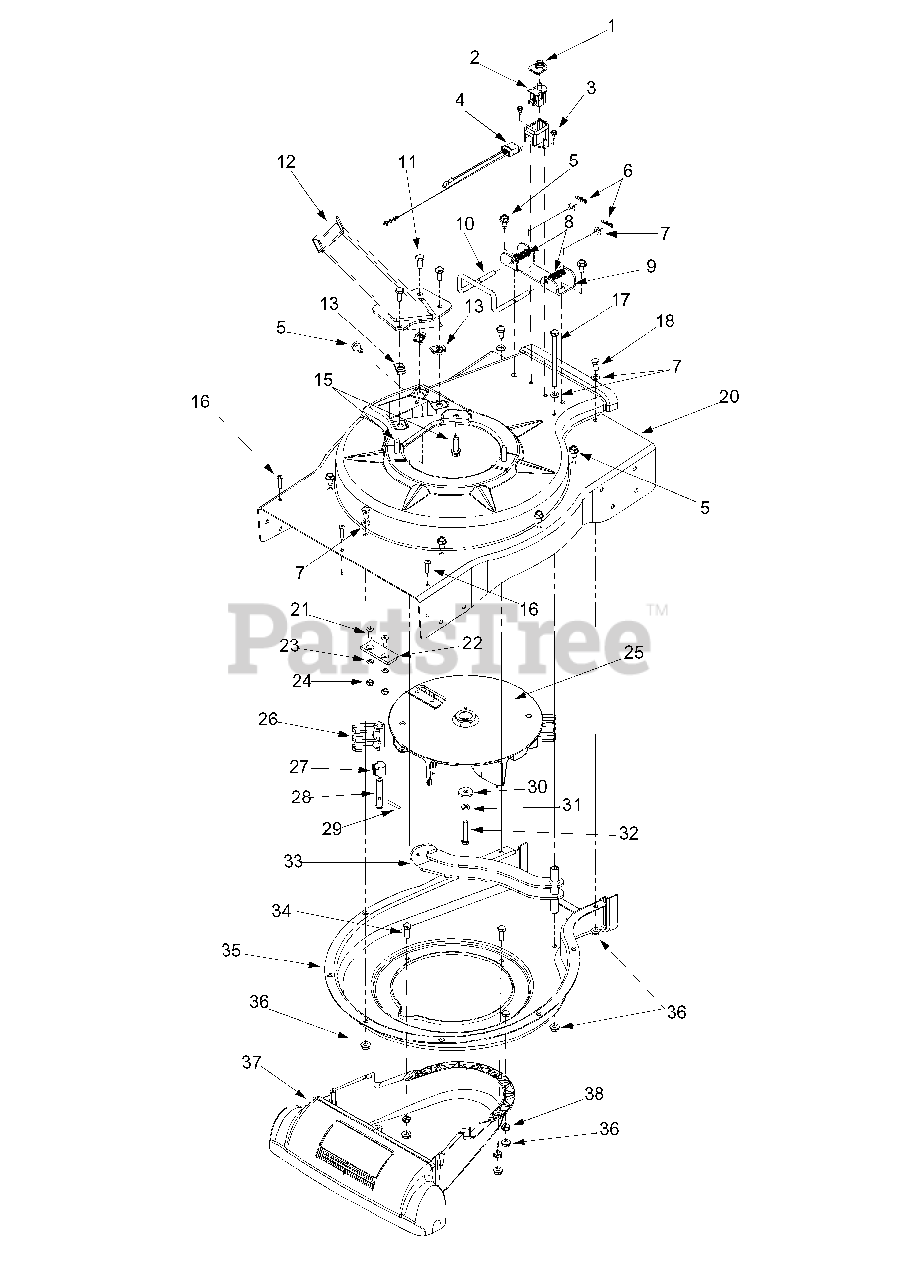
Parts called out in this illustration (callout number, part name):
1	Switch Cover
2	Safety Switch
3	Hex Washer Screw #10-16 x .50
4	Wire Harness
5	Hex Washer Screw 5/16-18 x .625
6	Cotter Pin
7	Flat Washer .330 ID x .630 OD
8	Compression Spring
10	Lock Rod
11	Hex Cap Screw 5/16-18 x .75
13	U-Clip Lock Nut 5/16-18
15	Hex Washer Screw 3/8-16 x 1.25
16	Screw #12-16 x 1.0
17	Hex Cap Screw 5/16-18 x 4.5
18	Hex Cap Screw 5/16-18 x .625
22	Chipper Blade
23	Lock Washer 5/16
24	Hex Lock Nut 5/16-24
25	Impeller Ass'y
26	Flail Blade
27	Pin Clip
28	Clevis Pin
29	Spiral Pin
30	Flat Washer 3/8 ID x 1.25 OD
31	Lock Washer 3/8
32	Hex Cap Screw 3/8-24 x 2.0
34	Hex Cap Screw 5/16-18 x .875
36	Lock Nut 5/16-18
37	Nozzle Cover
38	Lock Nut 5/16-18
